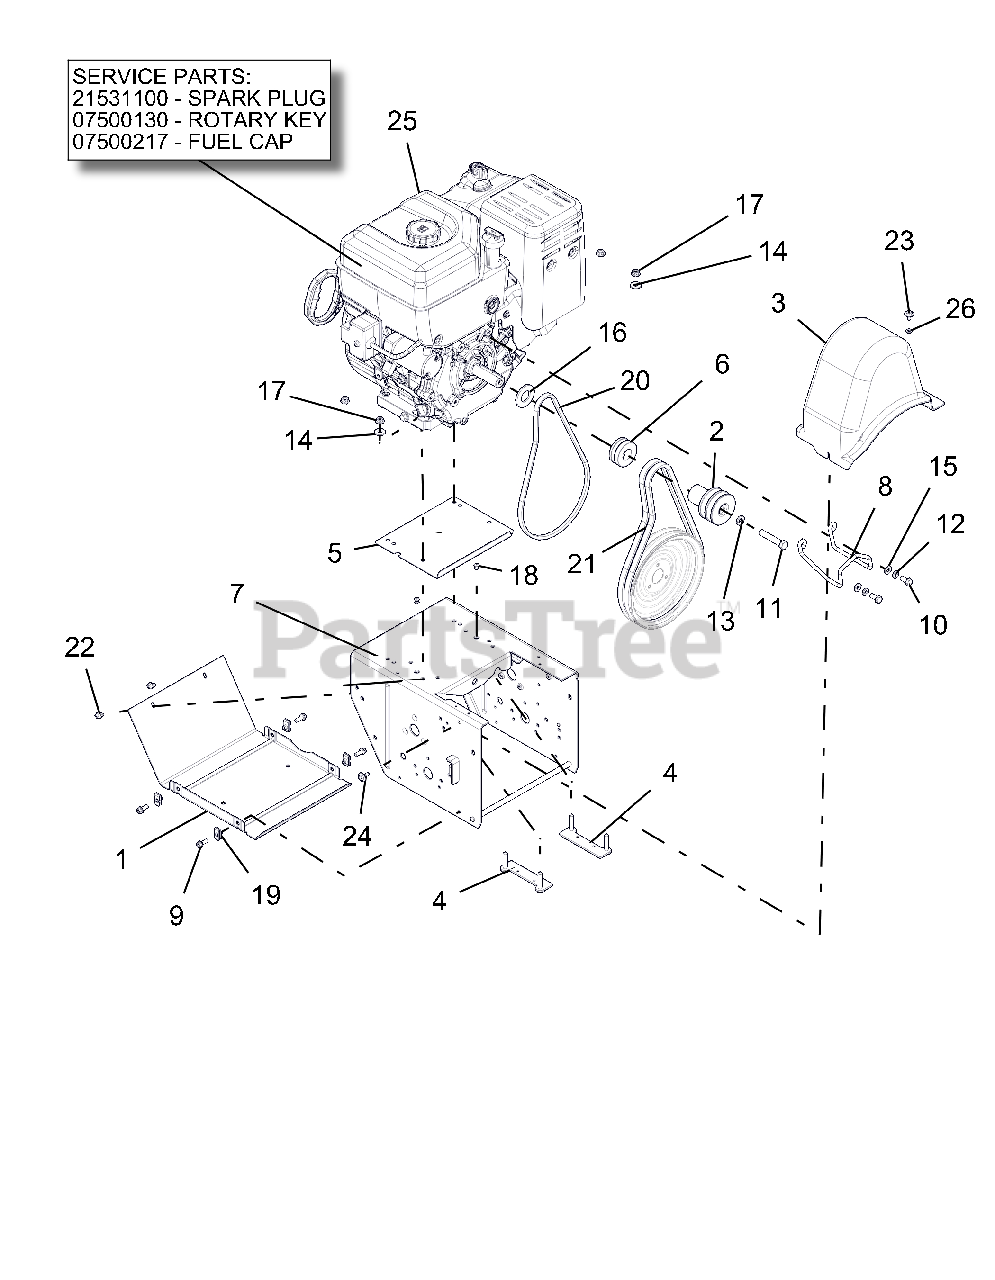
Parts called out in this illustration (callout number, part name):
1	COVER, BOTTOM
2	SHEAVE, ATTACHMENT 2-GRV
3	COVER, BELT-LARGE PRO
4	BOLT STRAP, 2100 BRIGGS
5	BAFFLE,ENGINE-PRO SERIES
6	SHEAVE, DRIVE 420 BRIGGS
7	PRO HYDRO FRAME, MAIN
8	FINGER, BELT
9	BLT-HEX .25-20X.75 HWH YZ GR5
10	BLT-HEX .31-24X.75 YWZC GR5
11	BLT-HEX .44-20X2.50 GR5 YWZC
12	WSHR-LK .312X.097 HVY YWZC
13	@WSHR-LK .44X.109 REG YWZC
14	@WSHR-FL-STL.38X.875X.083 YWZC
15	@WSHR-FL-STL.344X.688X.065YWZC
16	WSHR-FL-STL- 1.062X2.0X.134 YZ
17	@NUT-LK-CTR-FLG .31-18 YZ GR F
18	RVT-POP .187 YZ
19	NUT-RTNR .25-20X.56
20	V-BELT, 3L-WRAPPED
21	V-BELT, HA-RAW EDGE (SET)
22	SCR-TAP .25-20X.50 HWH TR YWZ
23	SCR-TAP .25-20X.50 LGHWH TR YZ
24	SCR-TAP .25-20X.5 CAPTIVE
25	ENGINE, BRIGGS PF 2100, 240V
25	PLUG, SPARK 20HP B&S VANGUARD
25	KEY, IGNITION ROTARY B&S
25	CAP, FUEL - BRIGGS & STRATTON
26	NUT-PUSH .25X.50 O.D.
